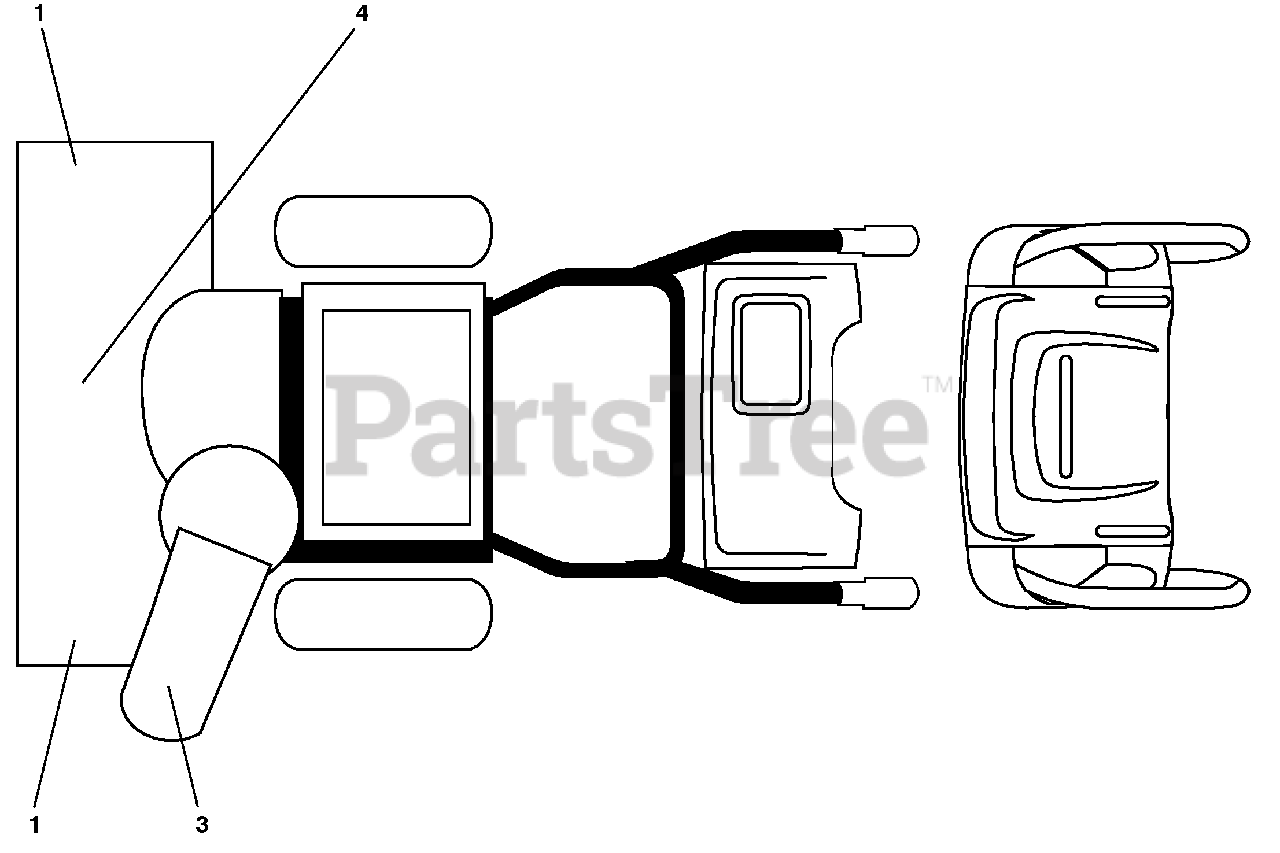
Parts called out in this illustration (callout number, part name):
1	DECAL, DANGER
3	DECAL, DANGER, DEFLECTOR
4	DECAL, DANGER
4	OWNER'S MANUAL, ENGLISH
4	OWNER'S MANUAL, FRENCH
